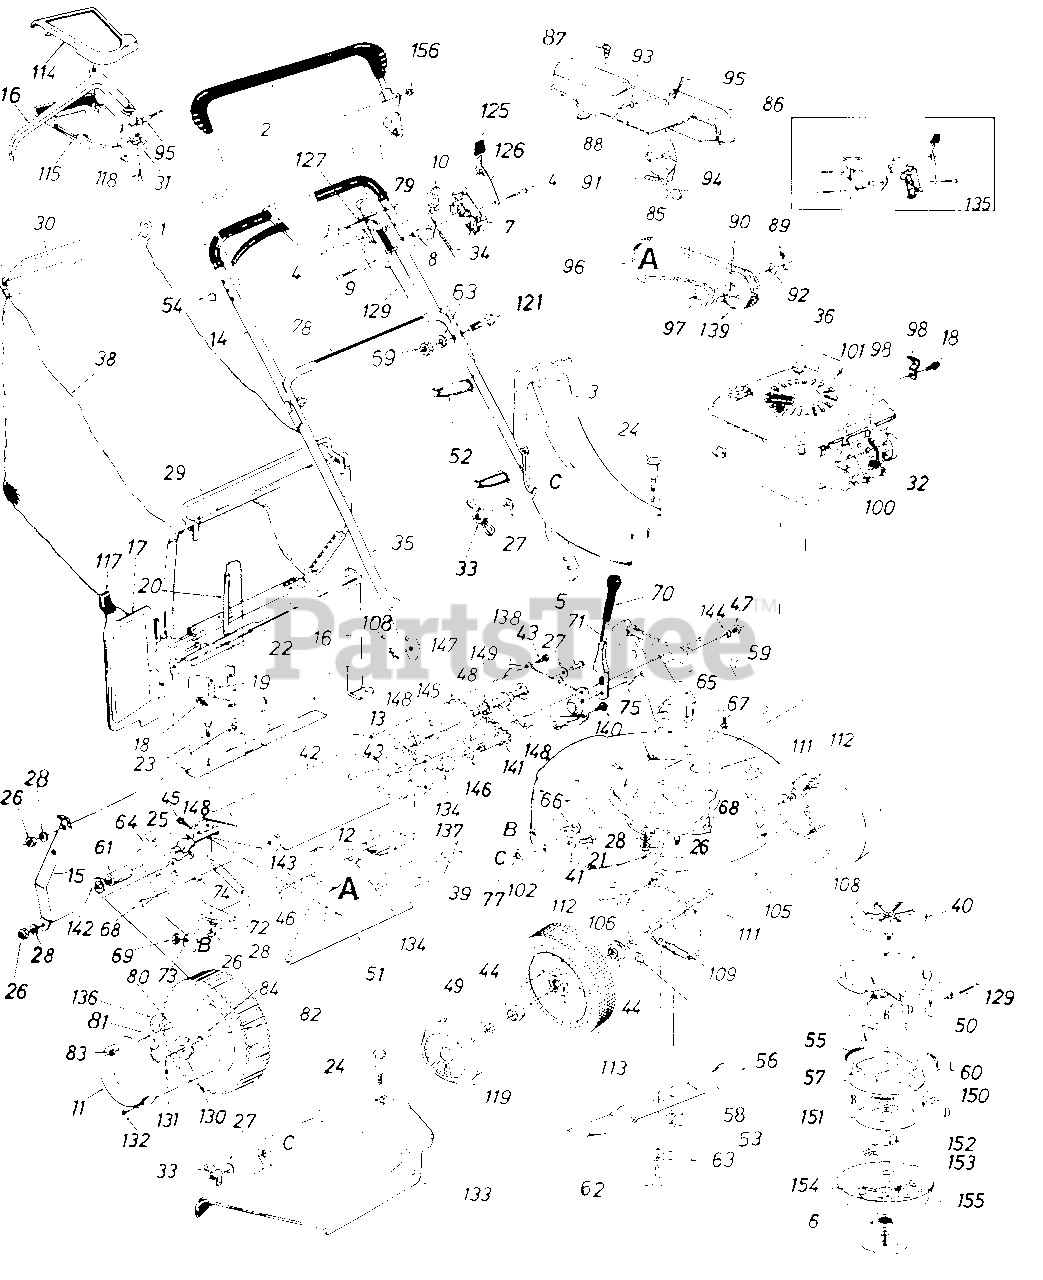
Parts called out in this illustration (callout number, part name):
1	Grip
2	Control Handle Ass'y. L.H.
3	Top Discharge Chute Ass y
4	Truss Mach. Scr. #12 x 1.50" Lg.
5	Hex Tap Scr. 1/4-20 x .75" Lg.
6	Ball Brg. .669" I.D. x 1.574"
7	Control Panel Half
8	Control Disc Pin
9	Clutch Panel Half
10	Throttle Control Lever
11	Hub Cap
12	1/2" V-Pulley
13	Cotter Pin 3/32" Dia. x .75"*
14	Upper Handle Chrome
15	Panel Support Brkt.
16	Top Catcher Panel
17	Top Door
18	Hex B-Tap Scr. #10 x .38"
19	Torsion Spring
21	Carriage Bolt 1/4-20 x .62"
22	Truss Mach. Scr. 1/4-20 x 1.0" Lg.
23	Hex Bolt 1/4-20 x .50" Lg.
24	Shoulder Bolt .312 Dia. x .18 Lg. Special
25	Hex Bolt 1/4-20 x .62" Lg.
26	Hex Nut 1/4-20 Thd.
27	Bell-Wash. 1/4" I.D.
28	L-Wash. 1/4" I.D.
29	Front Grass Catcher Frame
30	Grass Catcher Handle
31	S.P. Control Cover
32	Spark Plug Insulator
34	Throttle Control Wire 58"
35	Lower Handle Chrome
36	Engine
38	21" Top Discharge Grass Bag
39	Retaining Strip
41	Fl-Wash. .344" I.D. x .62"
42	Chain Axle Ass'y.
43	Hex B-Tap Scr. 1/4" x .38" Lg.
44	Flange Ball Bearing 1/2" I.D.
45	Hex AB-Tap Scr. 1/4 x .62"
46	Hex Wash. TT-Tap Scr. 1/4-20
47	Hex Patch L-Nut 3/8-24 Thd.
48	#48 Chain .500" Pitch x .30 0 Links
49	Hex L-Nut 1/2-20 Thd.
50	Clutch Housing
51	Rear Flap 3.75" x 17.30'1 Lg.
52	Cable Tie
53	Hex Nut 3/8-24 Thd. (Grade 8)
55	Extension Spring .35" O.D. x 1.75" Lg.
56	21 " Blade
57	Brake Cup Cone
58	L-Wash. 3/8" I.D.*
59	Height Adj. Rod 19.42" Lg.
60	Steel Ball .500" Dia.
61	Spacer .51" I.D. x .69" O.D. x.69" Lg.
62	Hex Cent. L-Bolt 3/8-24 x 2.0" Lg. (Grade 8)
63	Bell-Wash. 3/8" I.D.
64	R.H. Handle Wheel Brkt. Ass'y.
65	L.H. Handle Wheel Brkt. Ass'y.
66	Carriage Bolt 5/16-18 x .62"
67	Hex Wash. Hd. B-Tap Scr. 5/1 6-1 8
68	Hex Wash. Hd. TT-Tap Scr. 3/8- 1 6
69	Hex Nut 5/16-18 Thd.
71	Height Adj. Lever
72	Extension Spring .50" O.D. x 3.80" Lg.
73	Bell-Wash. .345" I.D. x .88"
74	Spacer .385" I.D. x .502" O.D. x .270" Lg.
75	Shld. Spacer.500" Dia. x . 100
77	Bolt Retainer 1/4 x .50" O.D.
78	Instruction Label
79	Control Label
80	Shld. Scr. .342" Dia. x .268
81	Pawl
82	Wheel Ass'y. Comp. Rear 8x 1.75
83	Hex Ins. L-Nut 1/4-20 Thd.
84	Flange Ball Bearing 1/2" I.D.
85	Belt Idler Bracket Ass'y.
86	Belt Cover
87	Hex Wash. S-Tap Scr. 1/4-20 x.50" Lg.
88	Hex Nut 1/4-20 Thd.
89	Cotter Pin 1/8" Dia. x 1.00"
90	Spring Pin Spir. 3/16" Dia. x 1.00" Lg.
91	Extension Spring .33" O.D. x 1.12" Lg.
92	Fl-Wash. .531' I.D. x .930" O.D. x .050
93	L-Wash. 1/4" I.D.
94	Shld. Bolt .375" Dia. x .181
95	S.P. Cable x 53.0" Lg.
96	"V"-Belt 1/2 " X 32.0" Lg .
97	Fl-ldler Plastic 1.62" Dia.
98	Casing Clamp
100	Hex B-Tap Scr. #10 x .62"
101	Casing Clamp
106	Sleeve .526" I.D. x .690" O.D. x .880" Lg.
108	Intern. Cotter Pin 5116" Dia.
109	Extension Spring .50" O.D. x 3.20" Lg.
111	Intern. L-Wash. 3/8 I.D.
112	Shld. Bolt .623" Dia. x .425
113	Front-Wheel Ass'y. Comp. 7x 1.50
114	Self-Propelled Control Cover
115	Self-Propelled Control Cover
116	Control Lever
118	Fl-"C"-Sunk Hd. Tap Scr. #10 x .75" Lg.
119	Hub Cap Plastic
121	Curved Carr. Bolt 5/16-18 x 1.38" Lg.
125	Spring Lever Knob
126	Lockout Spring
127	Lock Pin .314" Dia. x 1.75"
129	Blade Brake/Clutch Cable 46" Lg.
130	Ratchet Wheel 1.62" O.D.
131	Cotter Pin 118" Dia. x 1.00" Lg.
132	Pan Hd. Tap Scr. #12 x .50" Lg.
133	Side Chute Deflector Ass'y.
134	Flange Bushing
135	Kit Control Housing Comp.
136	Spring Nylon
137	Bearing Hub Flange Ass'y.
138	Chain Cover
139	Engine Pulley 1/2"
140	Hex Wash. S-Tap Scr. 1/4-20 x.50" Lg.
141	Sprocket Shaft Ass'y.
142	Fl-Wash. .531" I.D. x .93" O.D.
143	Bell-Wash. .265" I.D. x .75" O.D.
144	Fl-Wash. .385" I.D. x .37" O.D.
145	Fl-Wash. .51" I.D. x 1.0" O.D.
146	Fl-Wash. .62" I.D. x 1.12" O.D.
147	Rear Shaft Ass'y. 22.05" Lg.
148	Hex Flange Bearing .506" I.D. Plastic
149	Spacer .510" I.D. x 1.00" O.D. x .210" Lg.
151	Clutching Cone
152	Hex Tap L-Scr. 1/4-20 x .75" Lg.
153	Fl-Wash. .690" I.D. x 1.060" O.D.
154	Compression Spring .35" O.D. x 2.00" Lg.
155	Clutch Blade Housing Ass'y.
8204-000-7	Hardware Pack
